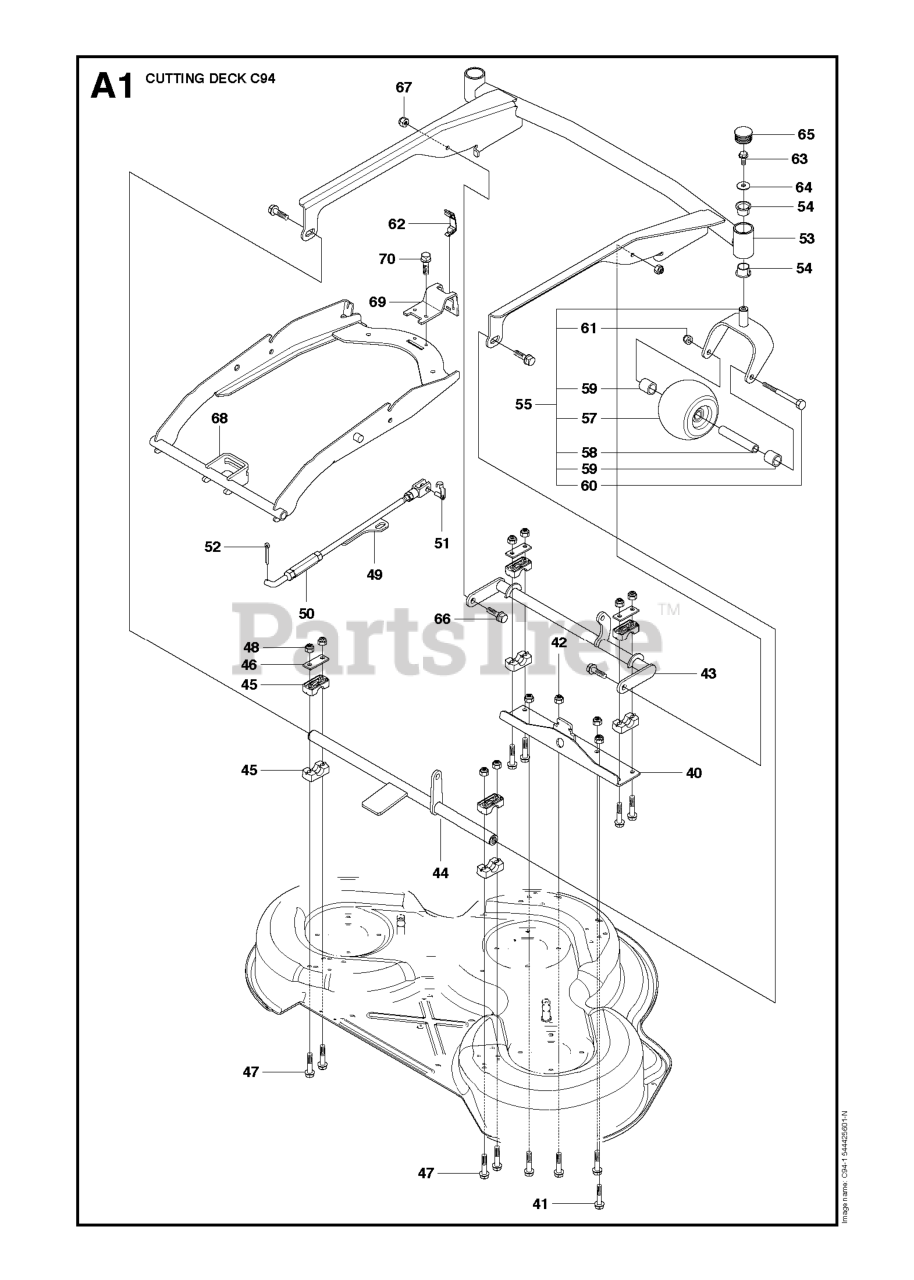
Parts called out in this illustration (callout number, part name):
42	LOCKNUT M8
43	PLATE
48	LOCKNUT M8
49	PARALLELL ROD ASSY
50	PARALLEL ROD
51	RETAINER
52	NUT
53	DECK FRAME
55	PIVOT WHEEL ASSY
57	DECK ROLLER, FRONT
57	E-RING
58	BOLT
59	LOCKNUT M8
60	DECK ROLLER, FRONT
61	WASHER
61	NUT
62	RETAINING RING SGA 15
62	CLIP GRAY
66	SCREW
67	SPACER
67	LOCKNUT M8
68	DECK ATTACHMENT
68	COLLAR SCREW
69	CLIP GRAY
70	SCREW
